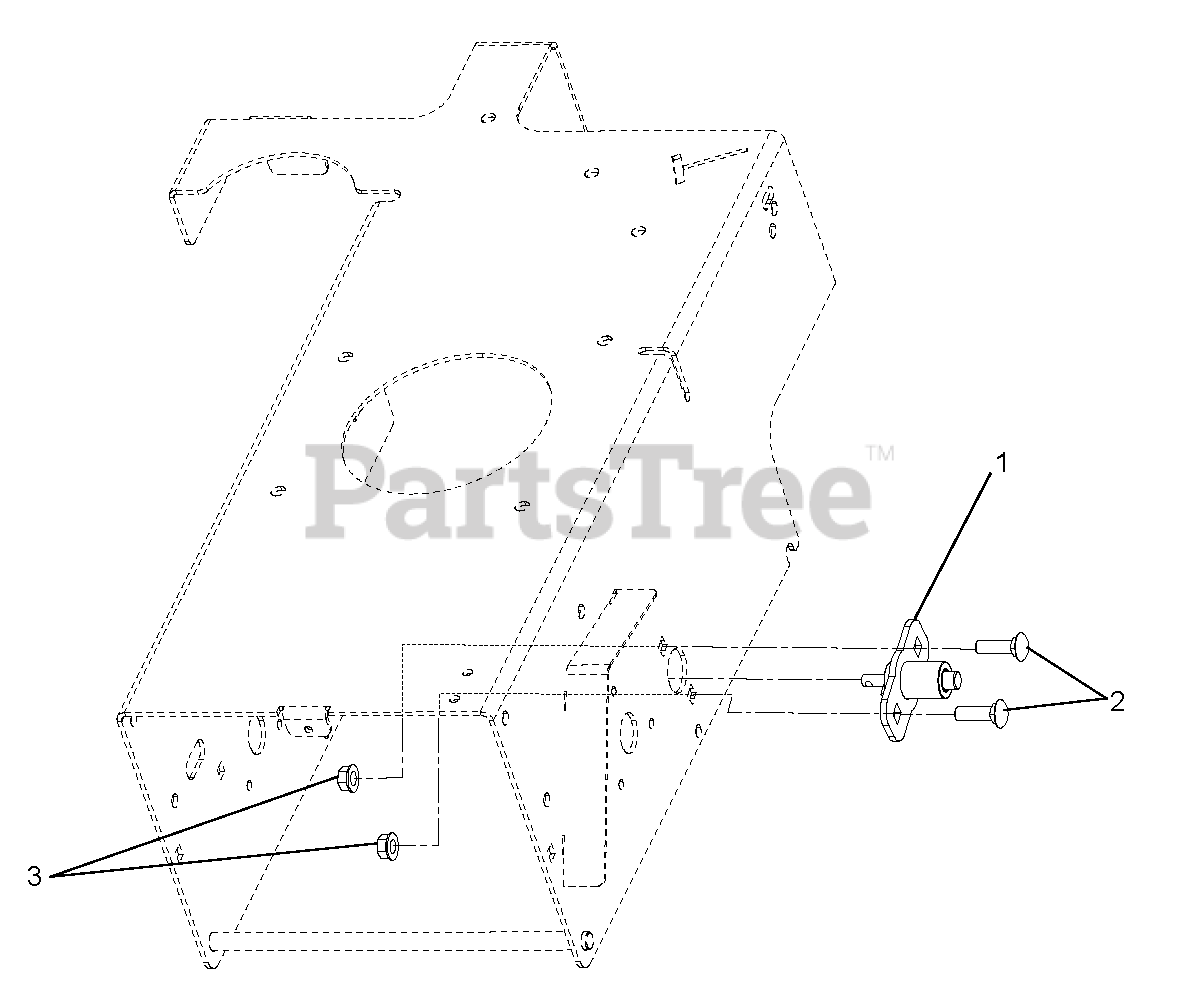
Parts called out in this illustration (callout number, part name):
1	Kit, Pin Brake
2	Bolt, Round Head Square Neck .38-16 x 1.25 Grade 5
3	Nut, Flange .375-16
